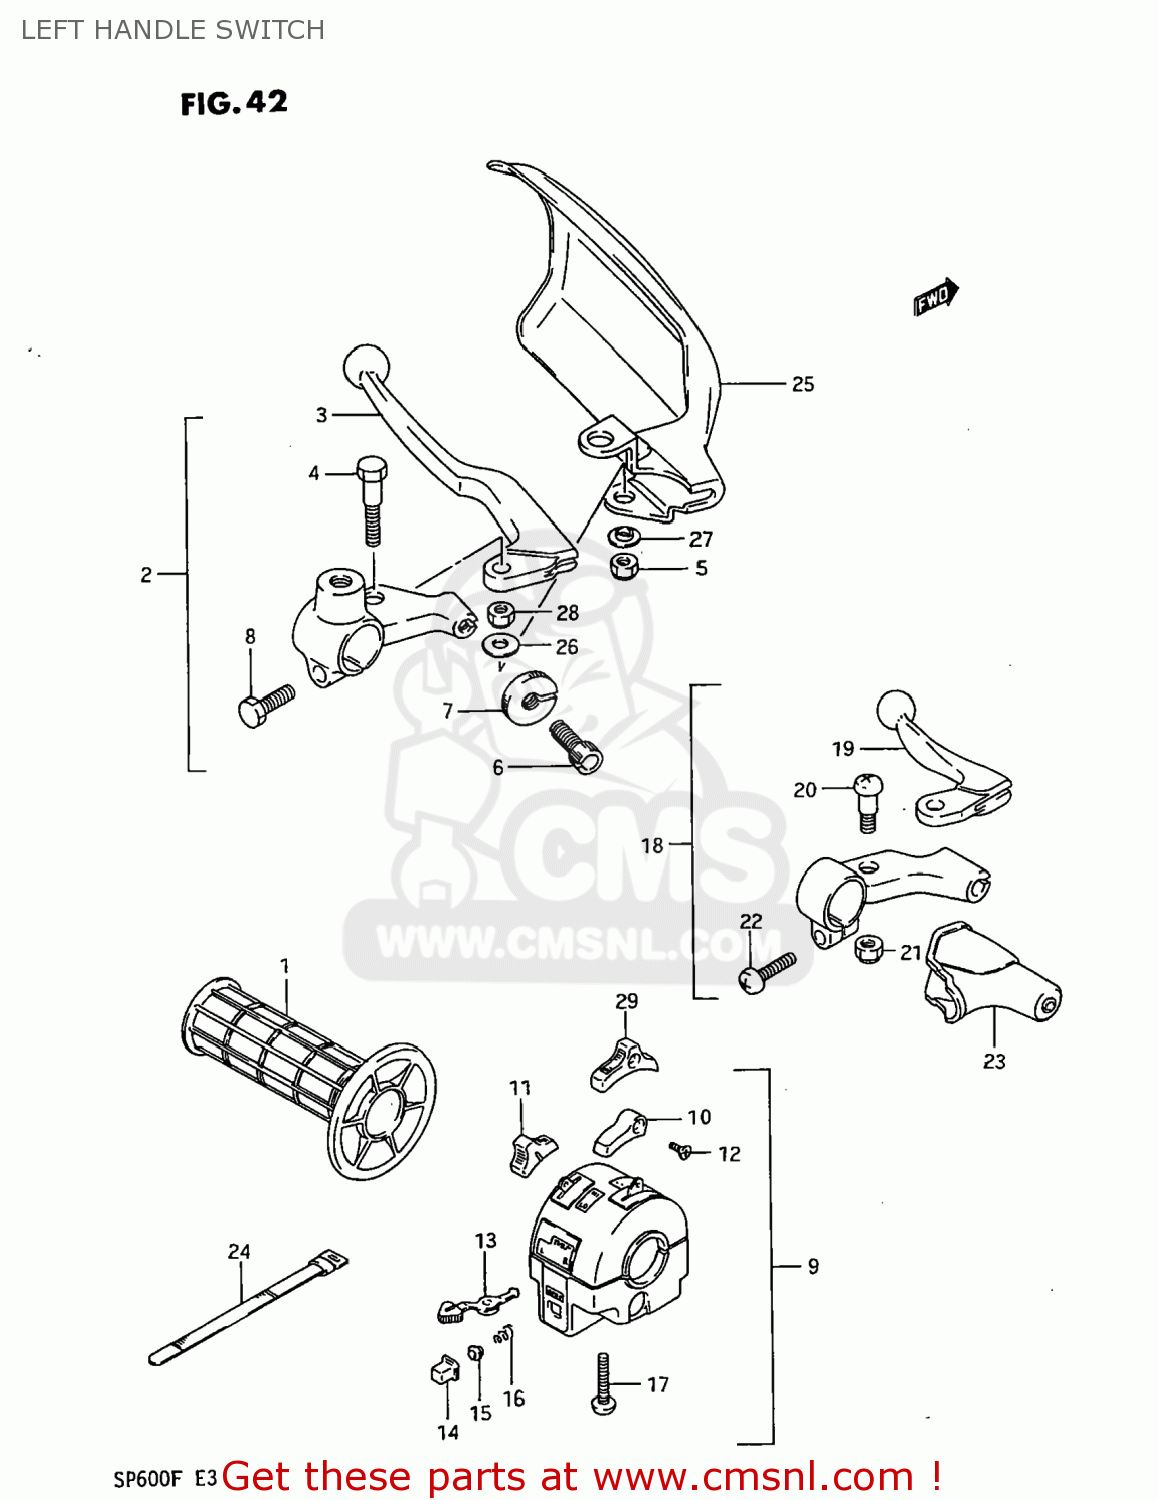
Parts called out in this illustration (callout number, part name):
1	GRIP,LEFT
2	LEVER ASSY,CLUTCH
3	LEVER,CLUTCH
4	BOLT,LEVER PIVOT
5	NUT
6	ADJUSTER,CABLE
7	NUT,CABLE ADJUSTER LOCK
8	BOLT
9	SWITCH ASSEMBLY,HANDLE,LEFT
10	KNOB,STOP
11	KNOB,DIMMER SWITCH
12	SCREW
13	KNOB,TURNSIGNAL
14	BUTTON,HORN
15	CONTACT
16	SPRING
17	SCREW
18	LEVER ASSEMBLY,DECOMPRESSION
19	LEVER,DECOMP
20	BOLT,LEVER
21	NUT
22	SCREW
23	COVER,DECOMP LEVER DUST
24	CLAMP(L:120)
25	COVER,KNUCKLE,LEFT
26	WASHER(6.5X16X1.2)
27	WASHER
28	NUT 6MM
29	KNOB,LIGHTING SWITCH
